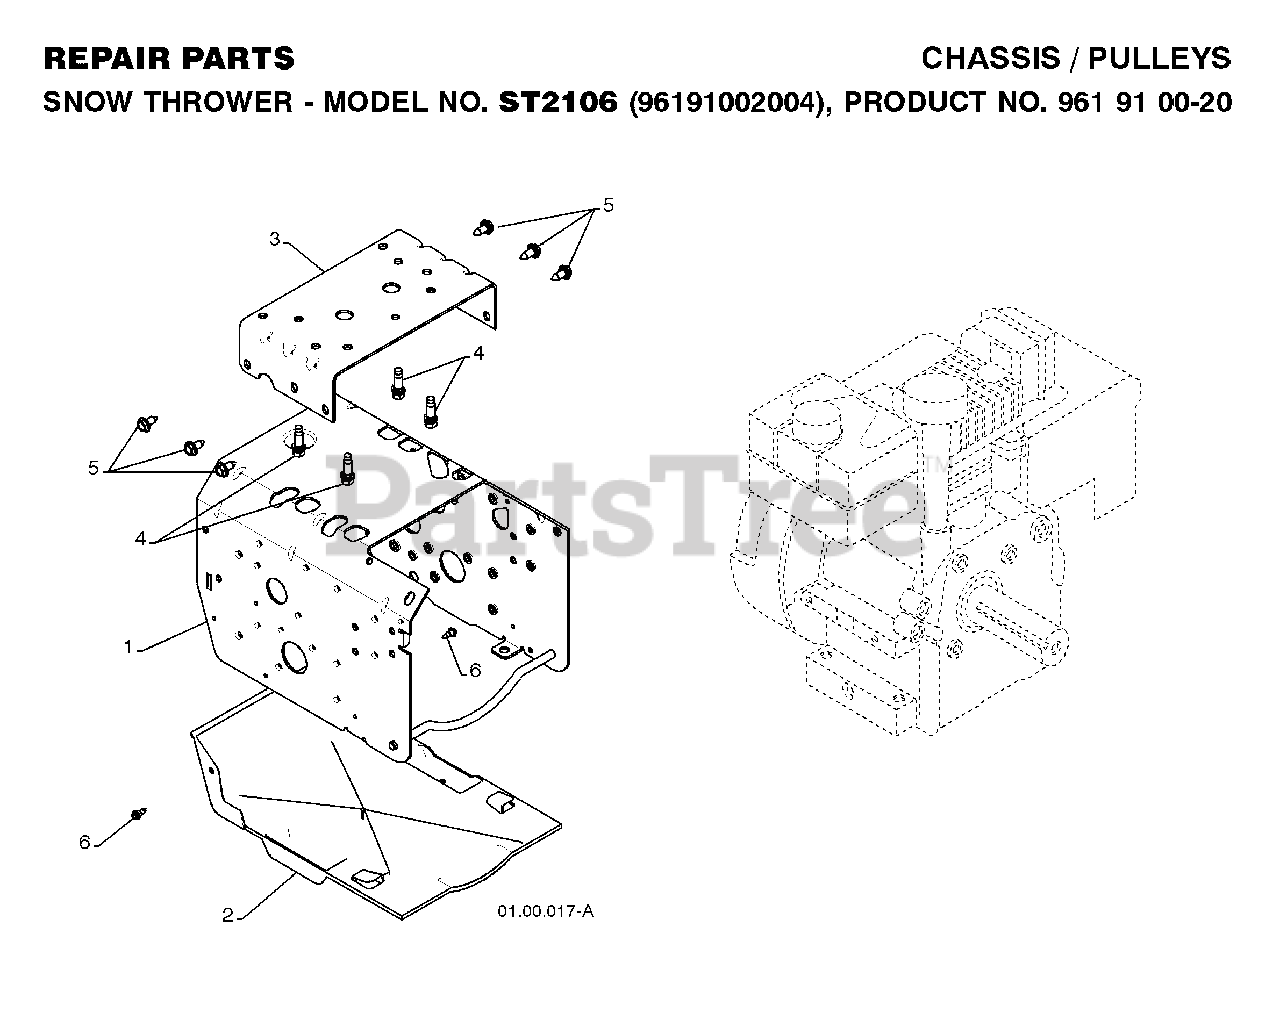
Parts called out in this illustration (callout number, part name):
2	PAN.BOTTOM.PLASTIC
4	BOLT 3/8-16X1-1/8
5	SELF-TAPPING SCREW 5/16-18X3/4
6	SCREW, HEX HEAD, TAPPING
